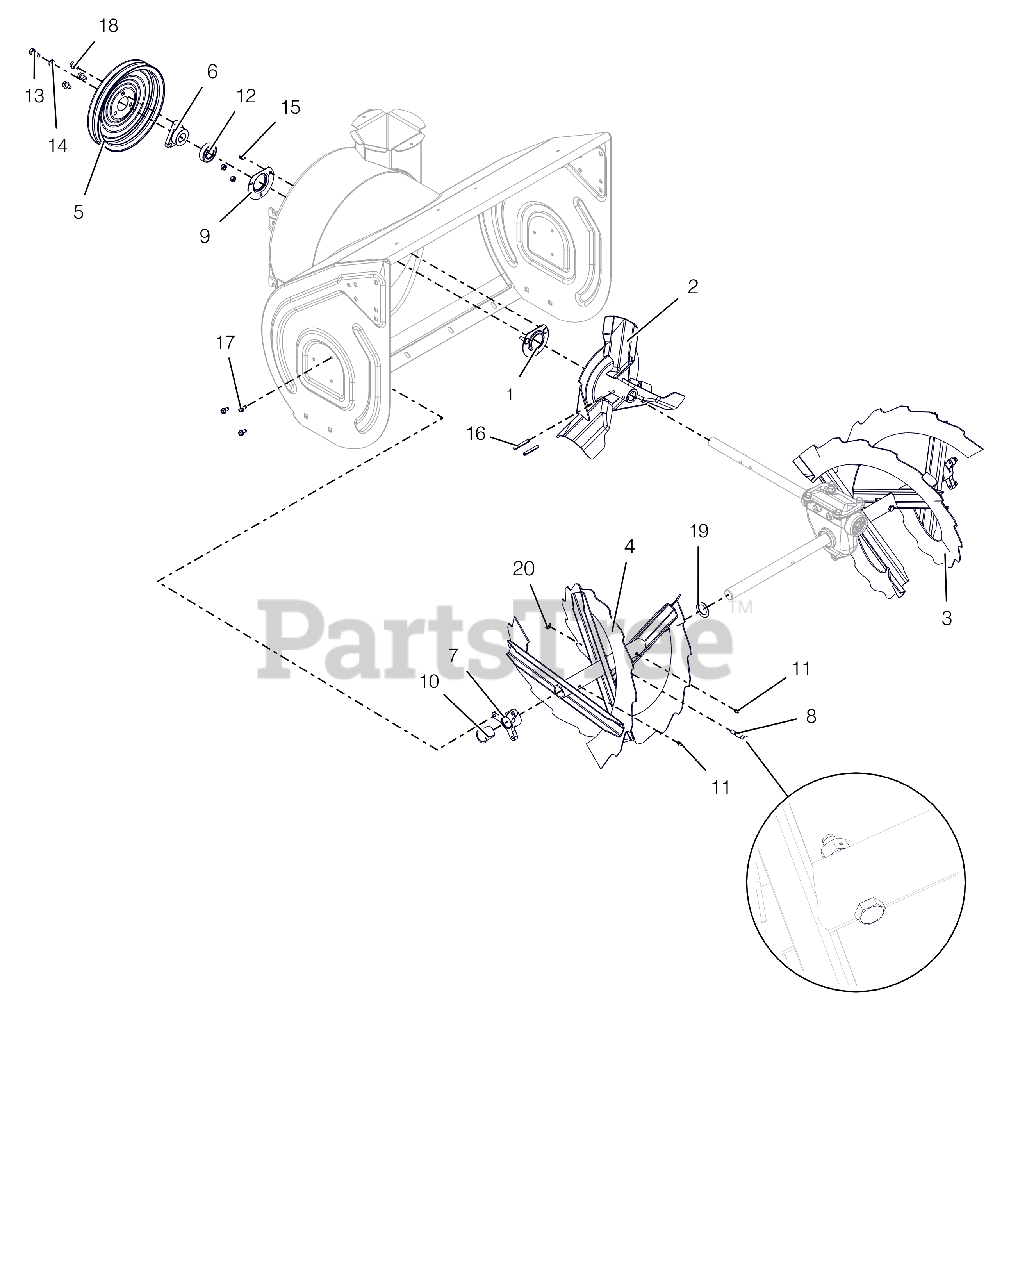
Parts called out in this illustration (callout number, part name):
1	BEARING FLANGE
2	IMPELLER, 3 BLADE-14"
3	RAKE, LH-28"(1 ID X 15.75 OD)
4	RAKE, RH-28"(1 ID X 15.75 OD)
5	PULLEY, SPIN FORM DUAL GROOVE
6	PULLEY HUB, D-BORE .87 PRO
7	BUSHING, RAKE SHAFT 1"
8	BOLT, SHEAR - DELUXE
9	BEARING FLANGE
10	BSHG-FLG SPLIT NYLINER 1.0" HP
11	ZERK,FITTING .25X.125 DRIVE IN
12	BRG-BALL .876X1.75X.50 RSTFP
13	BLT-HEX .31-24X.75 YWZC GR5
14	WSHR-LK .312X.097 HVY YWZC
15	@NUT-LK-CTR .25-20 YWZC
16	PIN-ROLL .250X1.75
17	SCR-TAP .25-20X.50 HWH TR YWZ
18	@SCR-TAP .31-18X.50 HWH TR YWZ
19	WSHR-FL-STL 1.010X1.505X.062YZ
20	@NUT-LK-CTR .31-18 YWZC
